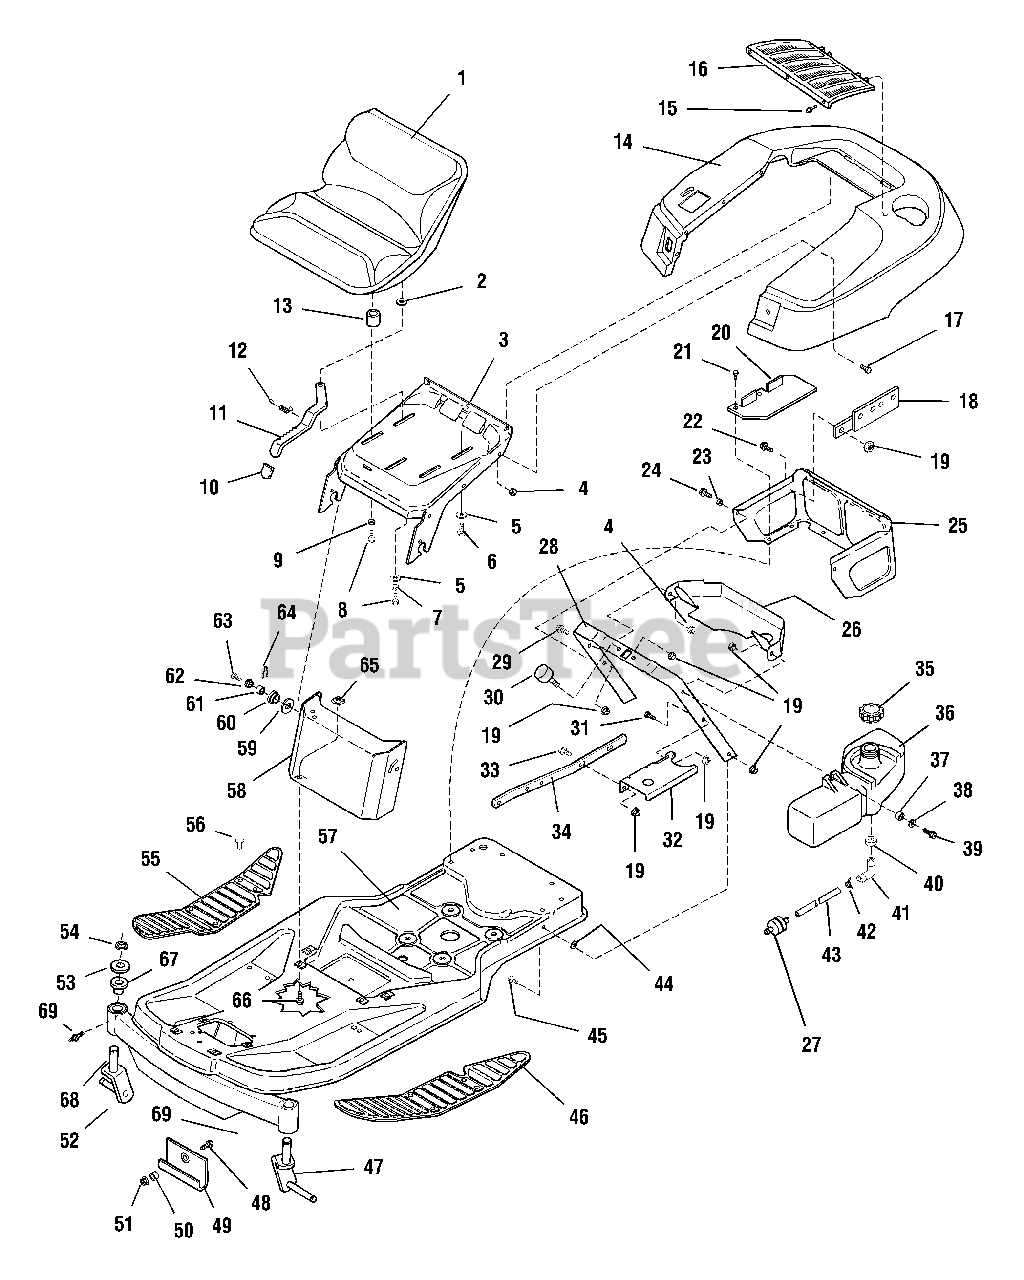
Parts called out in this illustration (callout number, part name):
1	SEAT, High Back, Replacement
3	SUPPORT, Seat
4	NUT, Hex Flange Lock, 1/4-20
5	WASHER, Plain
6	CAPSCREW, Hex Lock, 5/16-18 x 3/4
7	LOCKWASHER, 5/16
8	CAPSCREW, Hex, 5/16-18 x 1-1/4
9	NUT, hex, 5/16-18
11	ADJUSTER, Seat
13	SPACER, Seat Slide
14	DECK, Seat (Orange)
14	DECK, Seat (Red)
16	SCREEN
17	CAPSCREW, Hex Flange Lock, 1/4-20 x 5/8
18	SUPPORT, Reservoirs
19	NUT, Hex Flange Lock, 5/16-18
20	PLATE, Battery
21	CAPSCREW, Taptite, 1/4-20 x 1/2
22	CAPSCREW, Hex Hd, 5/16-18 x 5/8
24	CAPSCREW, Hex Hd, 5/16-18 x 1-3/4
25	SHROUD, Rear
26	DUCT, Air Inlet
27	FILTER, Fuel
28	SUPPORT, Seat Deck
29	CAPSCREW, Hex Hd, 1/4-20 x 3/4
31	CAPSCREW, Hex Hd, 5/16-18 x 1
32	SUPPORT, Fuel Tank
33	CARRIAGE BOLT, 5/16-18 x 1
34	STRAP, Fuel Tank, Brace
35	CAP, Fuel Tank
38	WASHER
39	CAPSCREW, Taptite Washer Head, 5/16-18 x 1-1/4
40	BUSHING, Rubber
41	FITTING, Elbow
42	CLAMP, Hose
44	NUT, Push Pal, 5/16
45	CAPSCREW, Hex Flange Whiz Lock, 5/16-18 x 3/4
46	FOOTREST PAD, LH
47	SPINDLE ASSEMBLY, LH
48	CAPSCREW, Hex Hd, 1/2-13 x 1-1/2
49	HOOK, Mower
51	NUT, Flange Lock, 1/2-13
52	SPINDLE ASSEMBLY, RH
53	WASHER
54	E-RING Retainer
55	FOOTREST PAD, RH
56	FASTENER, Panel
57	FRAME ASSEMBLY
58	PANEL, Front
59	WASHER, Plain
60	SPACER, Hood, Plastic
62	PIVOT, Hood
63	CAPSCREW, Taptite, 5/16-18 x 1
65	NUT, Pal, 5/16-18
66	CAPSCREW, Hex Flange Whiz Lock, 5/16-18 x 3/4
67	BUSHING, Upper
68	BEARING, Lower
69	FITTING, Grease
